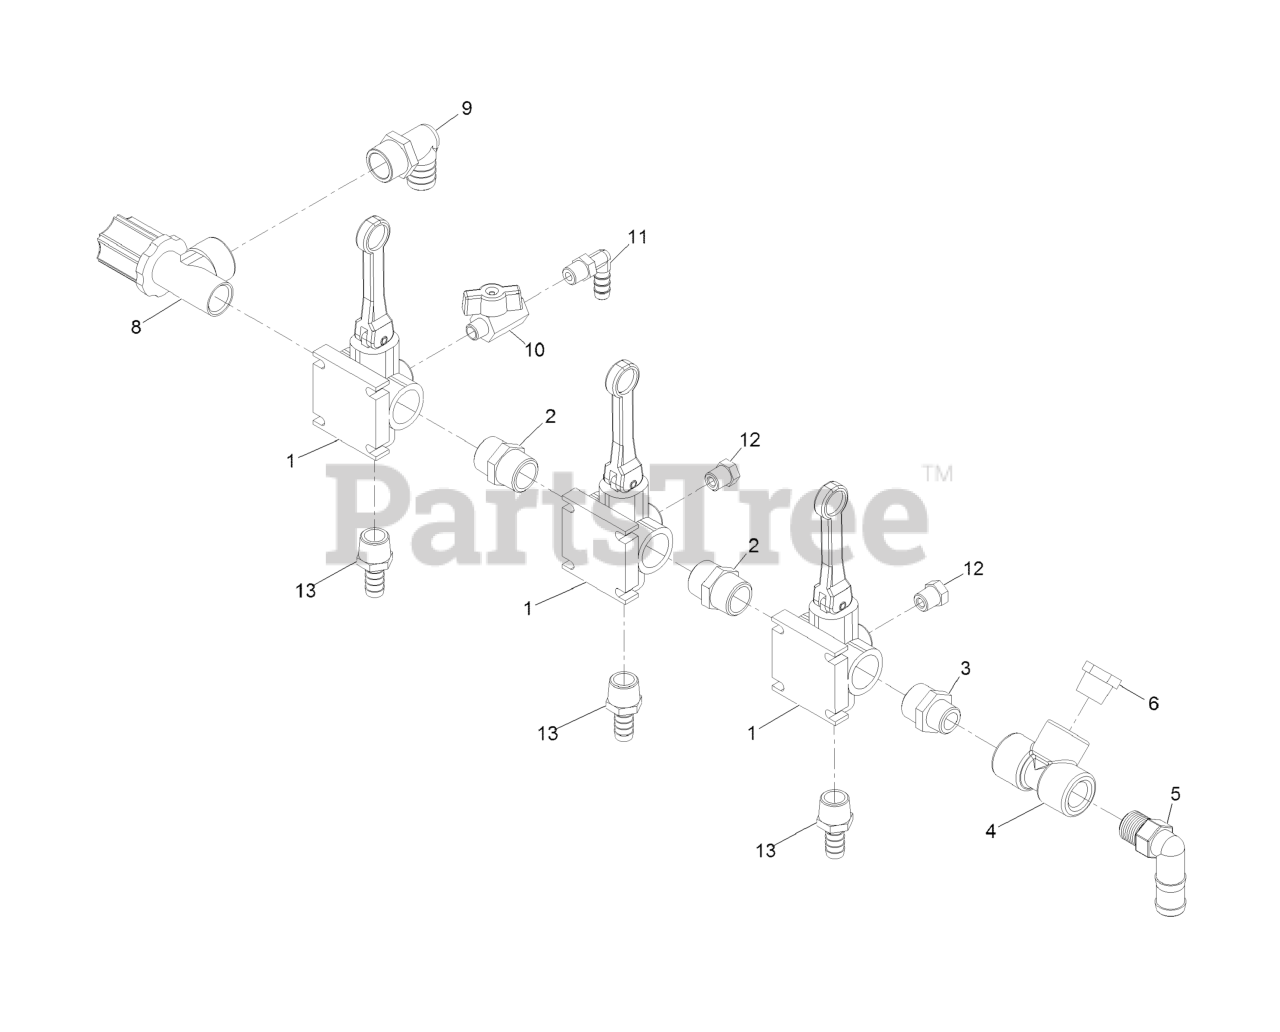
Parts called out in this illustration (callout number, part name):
1	VALVE-DIRECTO
2	FITTING-NIPPLE
3	FITTING-NIPPLE
5	ELBOW-90
6	FITTING-REDUCER
8	VALVE-THROTTLE
9	FITTING-ELBOW, 90
10	VALVE-CHROME, 1/4
11	FITTING-ELBOW, 90
12	PLUG-VALVE
13	FITTING-HOSEBARB
